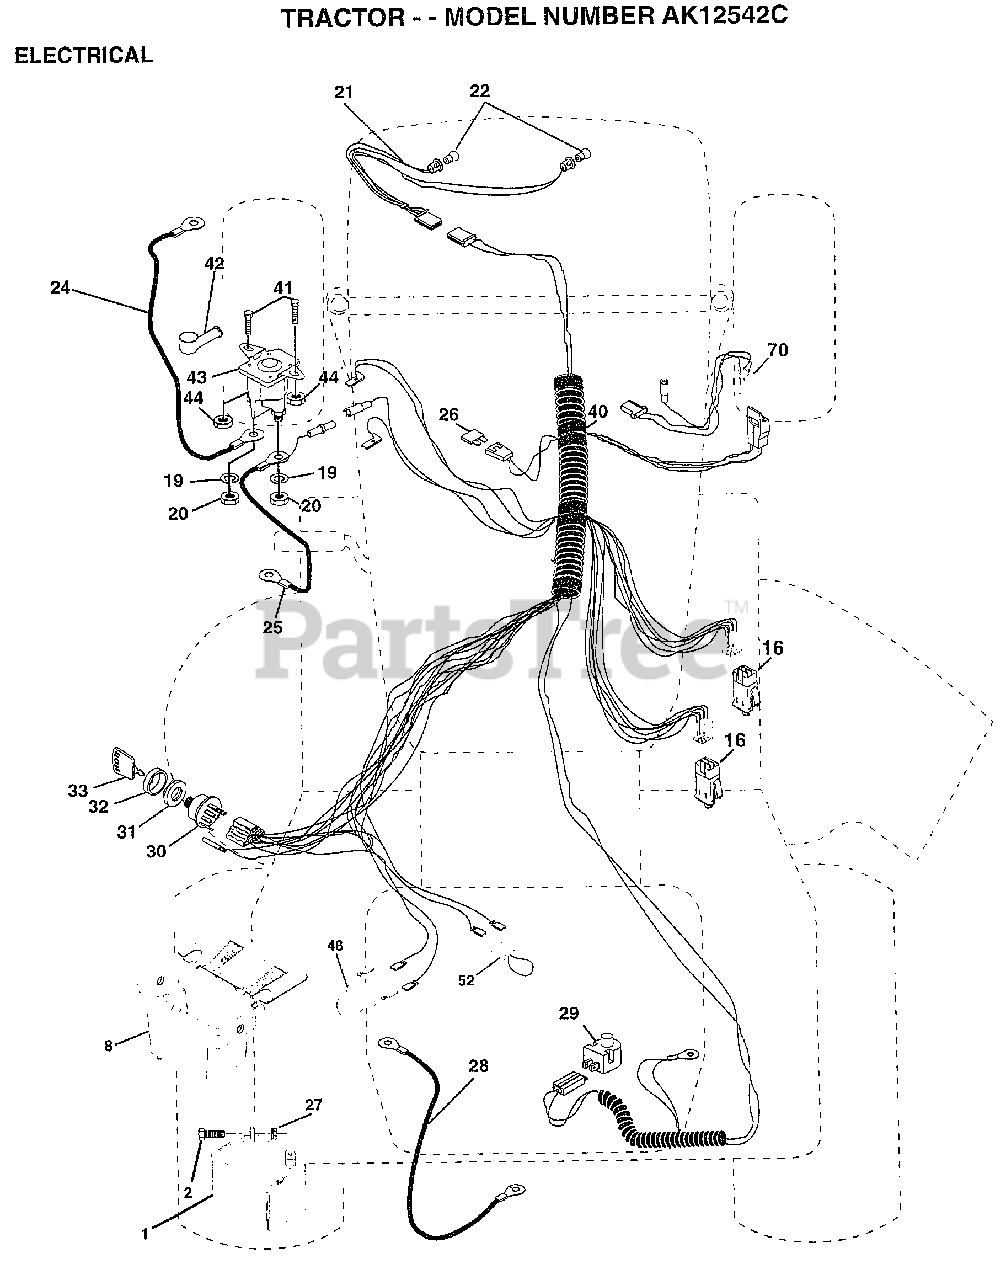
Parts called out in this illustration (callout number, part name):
2	BOLT LT
8	"CASE,BATTERY.MECH"
16	SWITCH INTERLOCK
20	NUT
21	HARNESS.ASM.LIGHT W/4152J
22	HEADLAMP BULB
24	"CABLE T, BATTERY"
25	CABLE.BTRY.6GA.RD
26	FUSE.15 AMP
27	NUT
28	CABLE T
29	SWITCH SEAT
30	SWITCH IGN 4POS
31	NUT IGNITION
32	COVER KEY SWITCH
33	KEY
40	HARNESS.IGNITION
41	BOLT HXHD FIN
44	NUT HXKEP 1/4X20
48	ADAPTER AMMETER
52	PROTECTION LOOP
70	HARNESS.ENGINE
